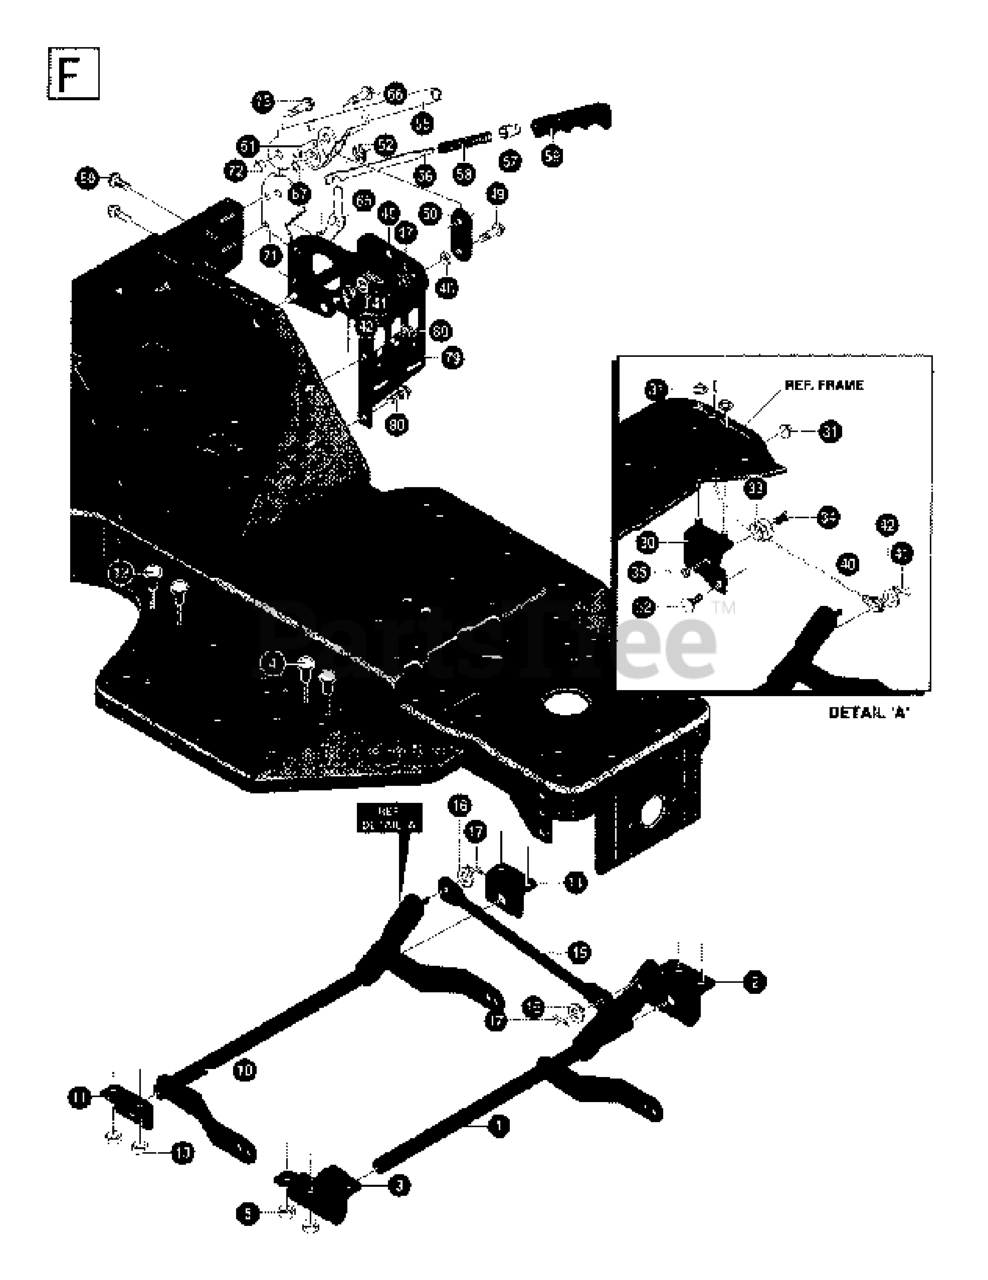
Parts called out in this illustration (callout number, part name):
4	SCREW
5	NUT
12	SCREW
13	NUT
15	REPL BY 533 30 23-89
16	WASHER
32	BOLT.CARR.SQNK.5/16-18UNC.X3/4
35	NUT
42	WASHER
47	NUT
48	WASHER
52	RETAINING RING
67	NUT
72	NUT
80	SCREW
